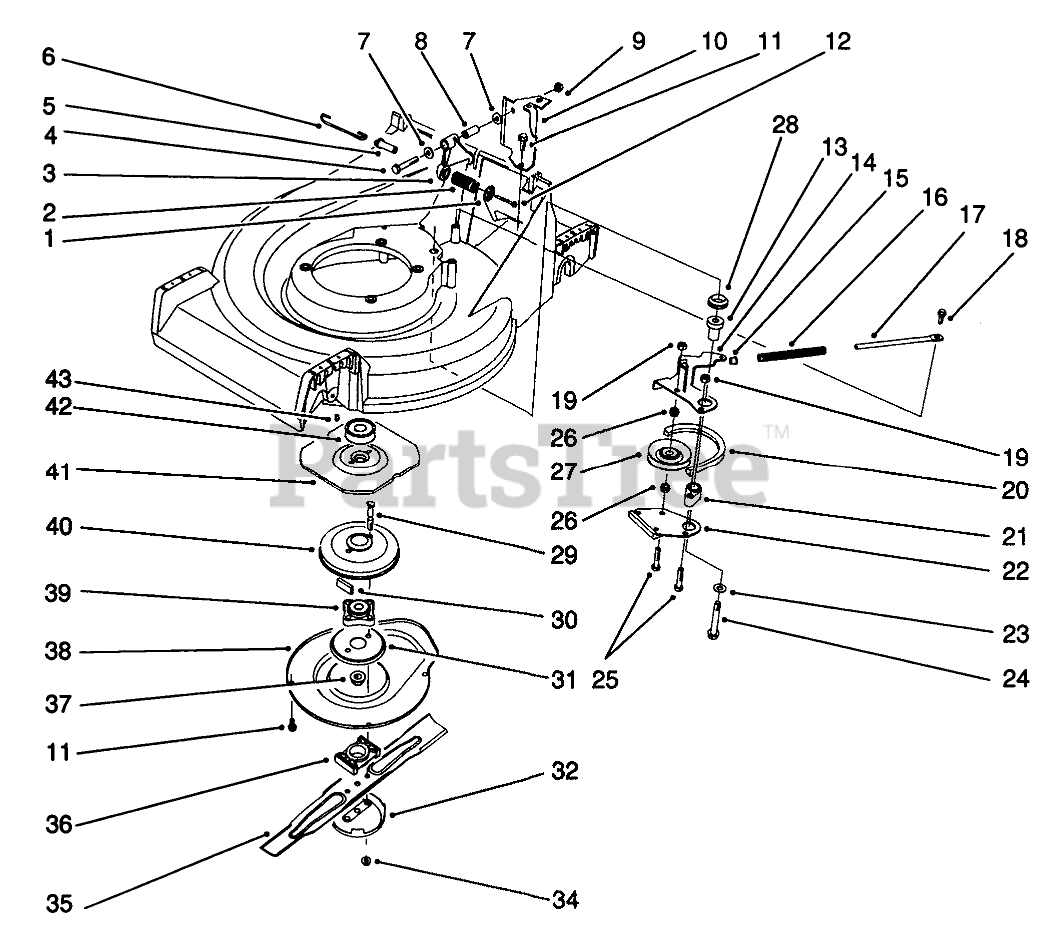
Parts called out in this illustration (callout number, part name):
1	RETAINER-SPRING
2	COMPRESSION SPRING
3	CRANK
4	SCREW-HH
5	SPRING PIN
6	CONTROL LINK
7	WASHER-PLAIN
8	STRAIGHT BUSHING
9	44 Nut-Lock
10	Bracket-Cable Support
11	SCREW-HWHTF
12	SCREW-HWHTF
13	BBC PM BUSHING
14	Lever
15	SPACER
16	COMPRESSION SPRING
17	SPRING ROD
18	SCREW-SHOULDER
19	NUT-LOCK, NI
20	V-BELT
21	BRAKE PLATE HUB
22	BRAKE SHOE
23	WASHER-PLAIN
24	3/8-16 X 2-3/4 CAPSCR
25	SCREW-HH
26	IDLER PULLEY HUB
27	PULLEY-IDLER
28	V-RING SEAL
29	BOLT-BLADE
30	DAMPENER-VIBRATION
31	Screen-BBC
32	CUP-SCALP, ANTI
34	NUT-LOCK
35	Key
36	SPACER-BLADE
37	NUT-LOCK, NI
38	Cover
39	HUB ASM
40	BRAKE DRUM
41	FLYWHEEL - BBC
42	PULLEY
43	KEY-WOODRUFF
